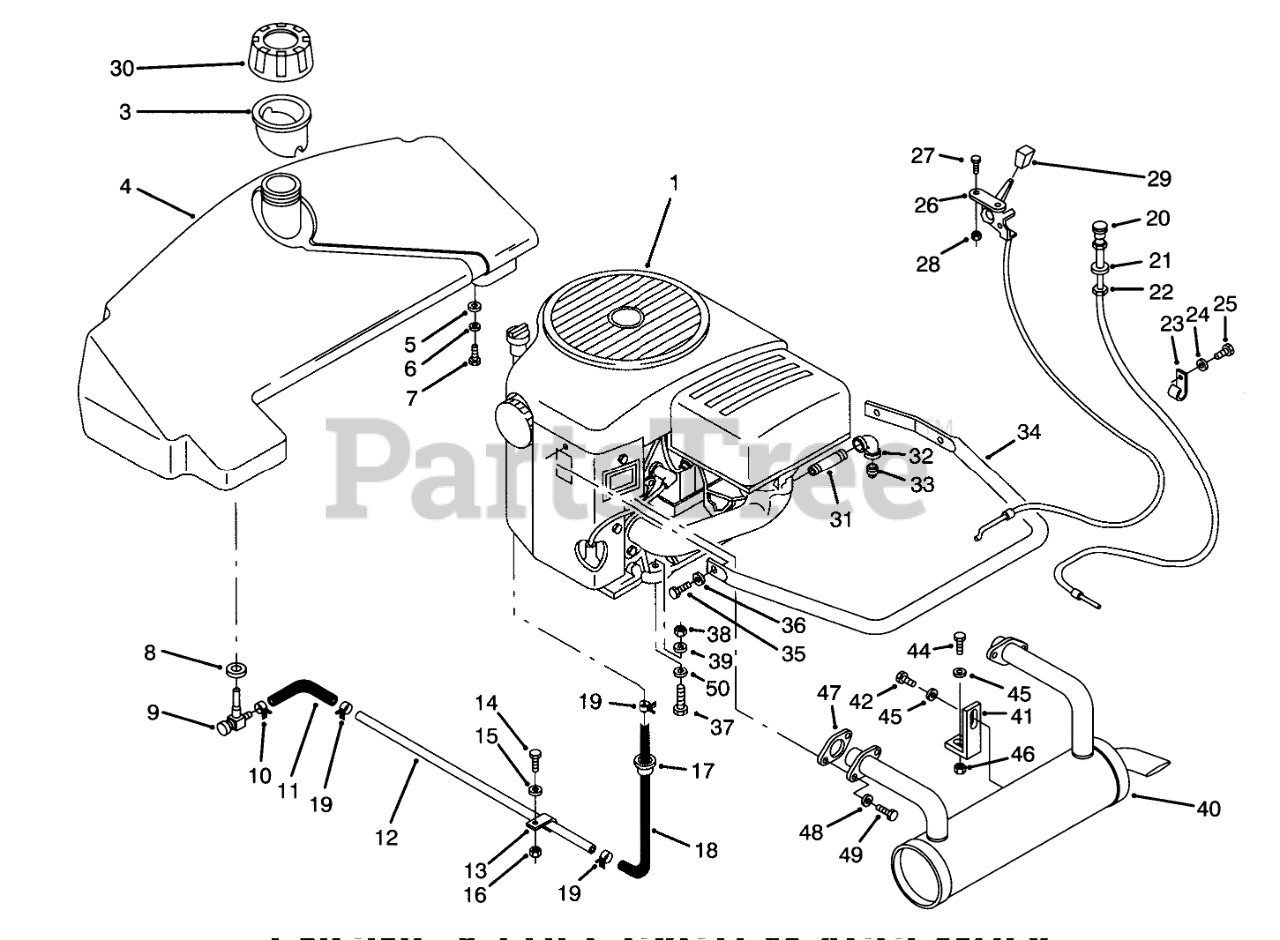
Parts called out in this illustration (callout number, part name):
1	Engine-16HP Model P216V-1/11103-D
3	FUNNEL-FUEL TANK
4	TANK-FUEL ASS'Y
5	WASHER-FLAT
6	WASHER-LOCK
7	SCREW-HH
8	BUSHING
9	VALVE-FUEL
10	Clamp
11	Hose5"
12	TUBE FUEL LINE
13	J-CLIP
14	SCREW-HH
15	WASHER-FLAT
16	NUT-LOCK, NI
17	BUSHING-NYLON 1.093
18	Fuel Hose 18"
19	CLAMP HOSE .5 IN
20	CONTROL-CHOKE
21	Washer
22	NUT-HEX PALNUT
23	CLIP
24	WASHER-LOCK
25	SCREW-HH
26	CONTROL-THROTTLE
27	Screw
28	Nut
29	KNOB-CONTROL
30	GAS CAP ASM
31	NIPPLE-3/8 X 2.5
32	ELBOW 3/8 90 DEG
33	Plug
34	GUARD-AIR CLEANER
35	SCREW-HH
36	WASHER-LOCK
37	SCREW-HH
38	NUT-LOCK, NI
39	WASHER-FLAT
40	EXHAUST-MUFFLER
41	BRACKET-MUFFLER
42	SCREW-HH
43	WASHER-FLAT
44	SCREW-HH
45	WASHER-FLAT
46	NUT-LOCK, NI
47	Exhaust Gasket
48	WASHER-LOCK
49	SHCS 5/16-18X.750
50	WASHER
